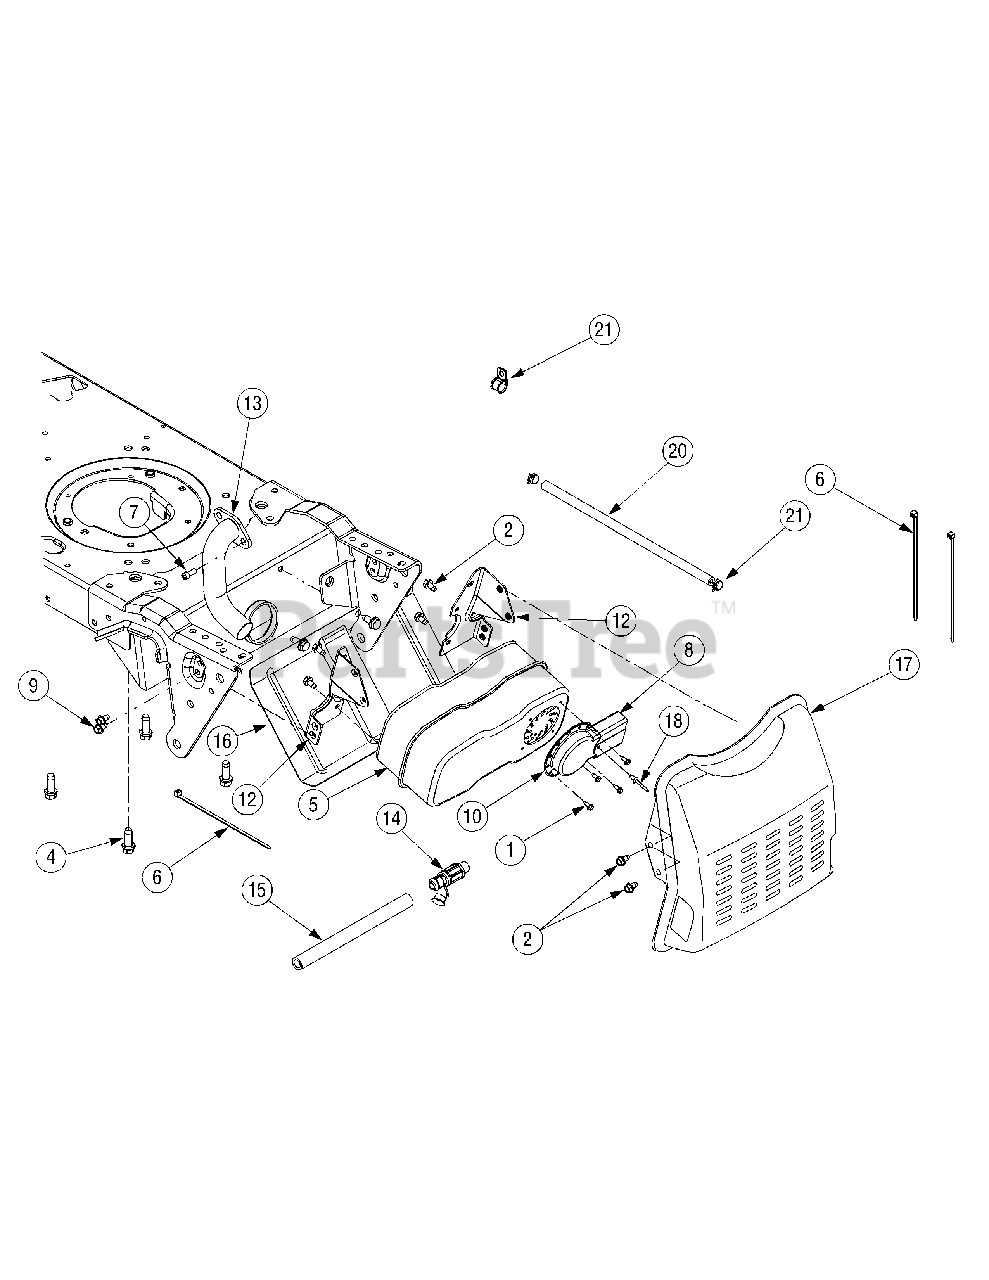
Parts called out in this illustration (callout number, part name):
1	Screw, #8-18, 0.500
2	Screw, Hex, 1/4-20, 0.500
4	Screw, Hex, 3/8-16 x 1.00
5	Muffler, Single Inlet
6	Cable, Tie, 3/16 x .05 x 7.4
7	Screw, 5/16-18, 0.75
8	Extension, Deflector
9	Screw, Hex, 1/4-20, 0.750
10	Deflector, Muffler
12	Muffler Bracket, LH
12	Muffler Bracket, RH
13	Pipe, Exhaust
15	Extension Hose, Oil Drain
16	Heat Shield, Lower
17	Shield, Muffler
18	Rivet, Pop, .188 x .325
19	Fuel Clamp
20	Fuel Line, Low Permeation
21	Clamp, 9/16
